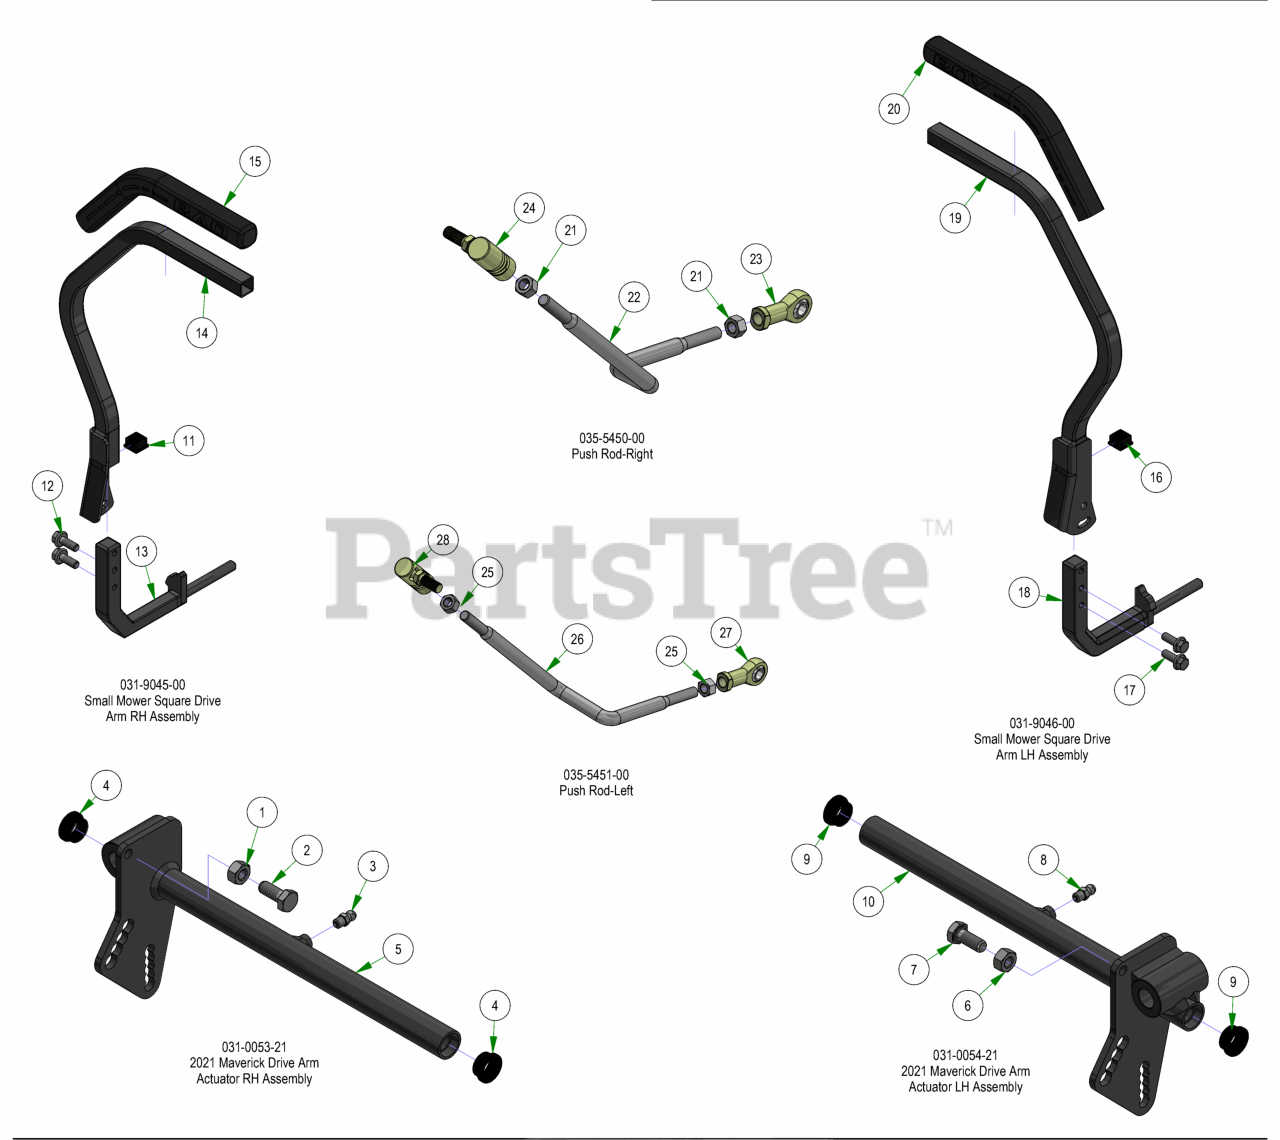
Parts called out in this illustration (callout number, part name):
1	5/16-18 HEX NUT ZINC
2	5/16-18 X 3/4 HEX CAP SCREW (GR.5) ZINC
3	1/4 DRIVE-TYPE STRAIGHT GREASE FITTING ZINC YELLOW)
4	2019 Drive Arm Bushing
5	2021 Drive Actuator RH Weldment
6	5/16-18 HEX NUT ZINC
7	5/16-18 X 3/4 HEX CAP SCREW (GR.5) ZINC
8	1/4 DRIVE-TYPE STRAIGHT GREASE FITTING ZINC YELLOW)
9	2019 Drive Arm Bushing
10	2021 Drive Actuator LH Weldment
11	9565K16_Polyethylene Square Plug
12	92323A554_Grade 5 Steel Serrated-Flange Hex Head Screw
13	Small Mower Square Drive Arm Lower RH Weldment
14	Small Mower Square Drive Arm RH Weldment
15	Grip for 031-9045-00 / 031-9046-00
16	9565K16_Polyethylene Square Plug
17	92323A554_Grade 5 Steel Serrated-Flange Hex Head Screw
18	Small Mower Square Drive Arm Lower LH Weldment
19	Small Mower Square Drive Arm LH Weldment
20	Grip for 031-9045-00 / 031-9046-00
21	3/8" Fine Threaded Jam Nut
22	Push Rod - Right (Rod Only)
23	Spherical Rod End - Outlaw
24	Quick Release Ball Joint
25	3/8" Fine Threaded Jam Nut
26	Push Rod LH (Rod Only)
27	Spherical Rod End - Outlaw
28	Quick Release Ball Joint
